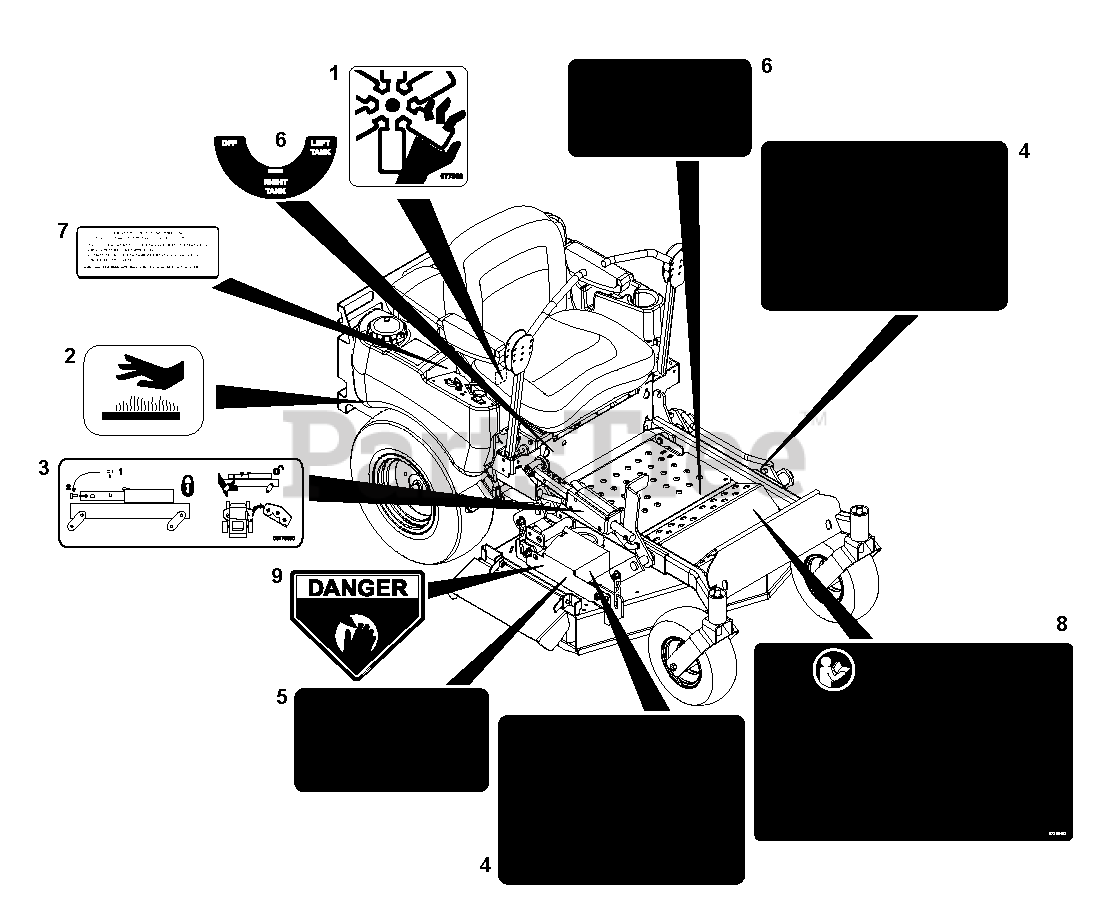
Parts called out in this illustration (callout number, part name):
1	Decal, Danger Fan
2	Decal, Hot Surface
3	Decal, Deck Service
4	Decal, Safety Mower Deck
5	Decal, Safety Deck Guarding
6	Decal, Safety Guarding
7	Decal, EPA
8	Decal, Main Safety Commercial
9	Decal, Danger
